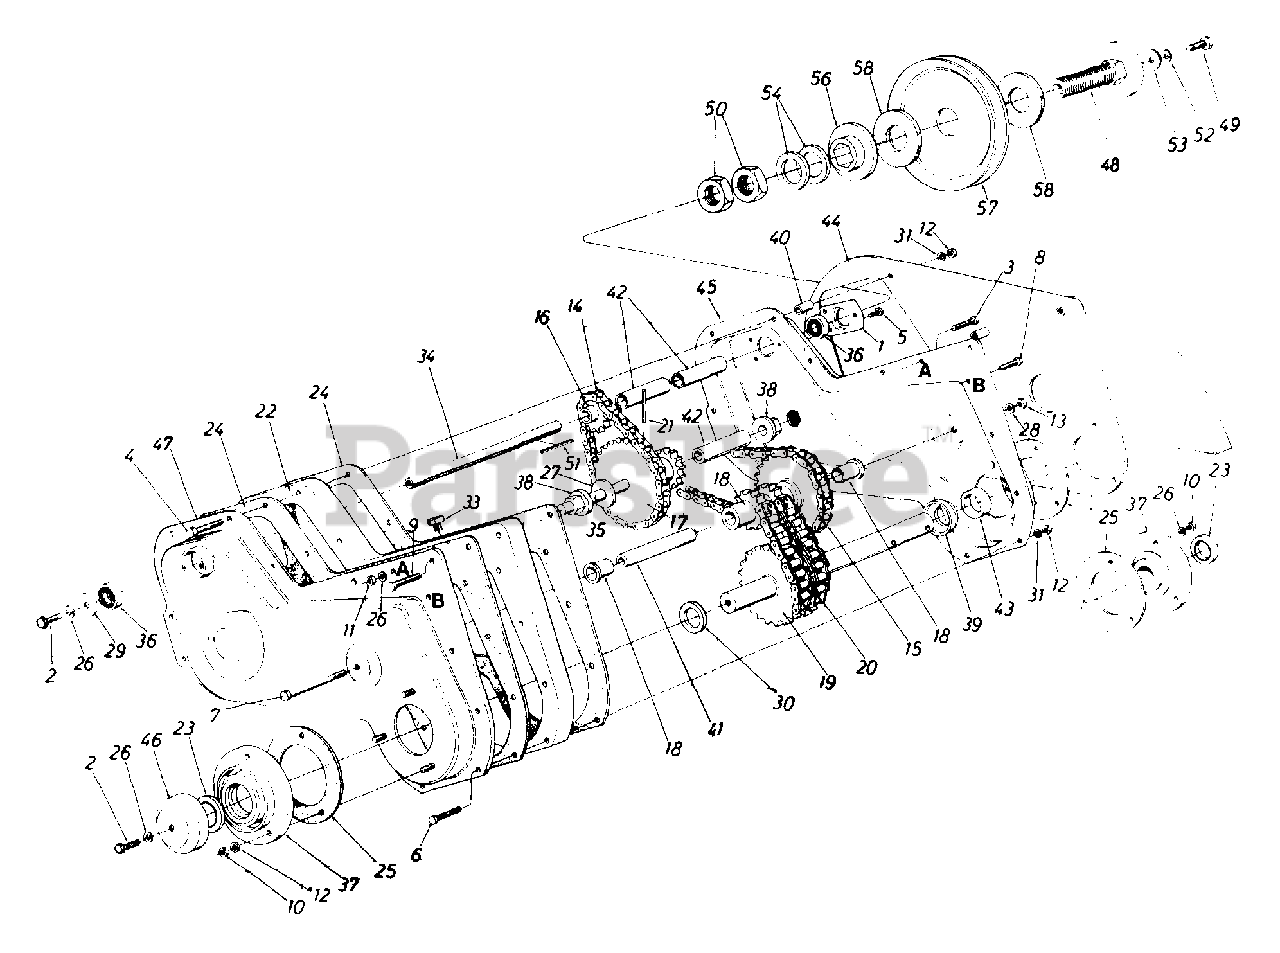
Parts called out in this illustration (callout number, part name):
1	Bearing Housing 1-3/8" Dia.
2	Hex Bolt 5/16-18 x .88" (Spec.)
3	Hex Bolt 5/16-18 x 1.5" Lg.
4	Hex Bolt 1/4-20 x 2.75" Lg.
5	Hex S-Tap Scr. 1/4-20 x .5" Lg.
6	Hex Bolt 1/4-20 x 1.5" Lg.
7	Hex Bolt 3/8-16 x 4.5" Lg.
8	Hex Scr. 1/4-20 x 1.5" Lg.
9	Hex TT-Tap Scr. 5/16-18 x 1.75"
10	Hex L-Nut 5/16-18 Thd.
11	Hex Nut 5/16-18 Thd.
12	Hex Nut 1/4-20 Thd.
13	Hex Nut 3/8-16 Thd.
14	#41 Chain 1/2" Pitch x 34 Links - Endless
15	#42 Chain 1/2" Pitch x 48 Links - Endless
16	Sprocket 10 Tooth .5" Pitch
17	10 & 28 Teeth Sprocket Ass'y.
18	8-2 & 28 Sprocket Sleeve Ass'y.
19	18-2 Sprocket Shaft Ass'y.
20	#50-2 Chain 5/8" Pitch x 28 Links - Endless
21	Spring Pin Spir. 1/4" Dia. x 1.5" Lg.
22	Spacer Block - Tiller Housing
23	Oil Seal 1-1/4" Dia.
24	Gasket for Tiller Housing
25	Gasket for Brg. Housing
26	L-Wash, 5/16" I.D.
27	Fl-Wash. .64" I.D. x 1.24" O.D.
28	L-Wash. 3/8" I.D. - H.D.
29	Fl-Wash. .344" I.D. x 1.125"
30	Special Washer
31	L-Wash. 1/4" I.D.
33	Vent Plug
34	Jack Shaft .525" I.D. x 7.78"
35	Sprocket Shaft .63" Dia. x 5"
36	Ball Brg. .62" I.D. x 1.38" O.D.
37	Bearing Housing - 1-1/4"
38	Hex Flange Brg,
39	Spacer 1.25" I.D. x 2.0" O.D.
40	Spacer .9" Lg.
41	Spacer 3.44" Lg.
42	Spacer .62" x
43	Spacer .5" Lg.
46	Dust Cap
49	Hex Bolt 5/16-18 x 1.25" Lg. Grade 5
50	Hex Jam Nut 1.0-14 x 28 Thd.
51	Sq. Key 3/16 x 1.5" Lg.
52	L-Wash. 5/16" I.D.
53	Fl-Wash. .344" I.D. x 1.125"
54	Bell-Wash. 1.0" I.D. x 2.0"
56	Floating Disc 3-1/4" O.D.
57	5/8 V-Pulley 1.5" I.D. x 6.5"
58	Friction Pad 3-1/4" O.D. x 1-3/8" I.D.
